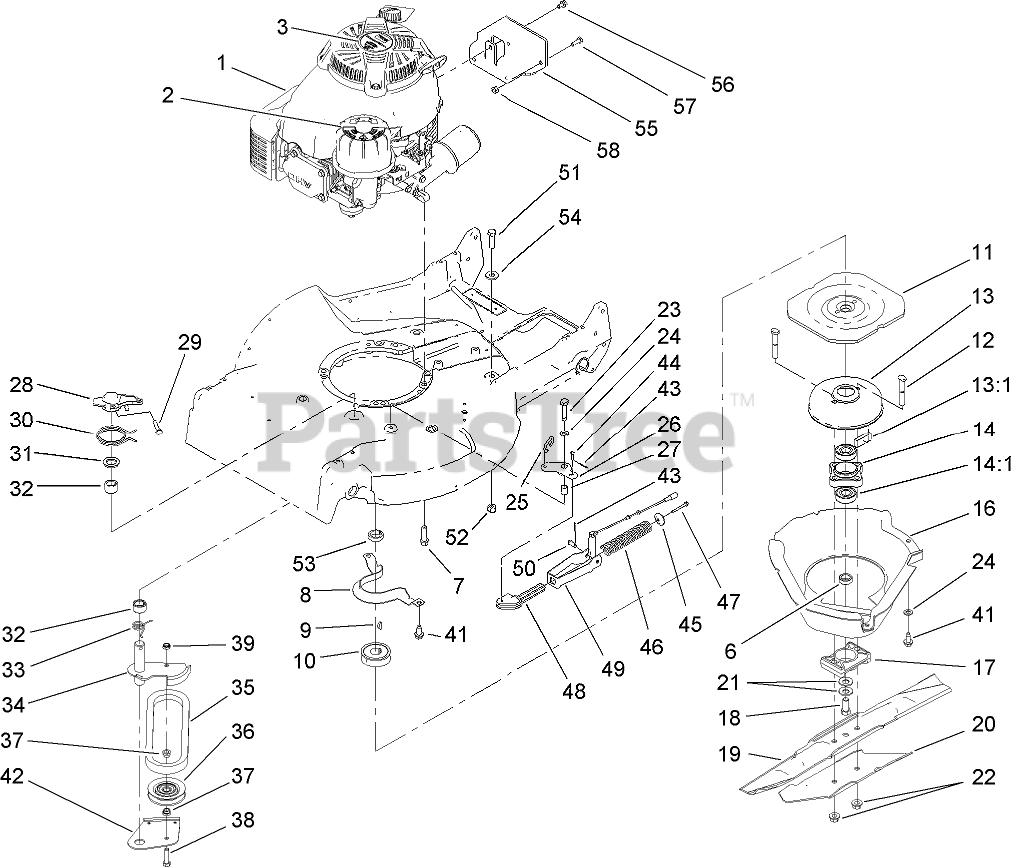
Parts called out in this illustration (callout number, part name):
1	ENGINE-KAWASAKI, FJ180V-AS36
3	DECAL
6	SPACER-SHAFT, OUTPUT
7	SCREW-TAPTITE
8	BRACKET-GUIDE, BELT
9	KEY-WOODRUFF
10	PULLEY-DRIVER
11	FLYWHEEL-BBC
12	BOLT-BLADE
13	BRAKE DRUM ASM
13:1	DAMPENER-VIBRATION
14	HUB ASM
14:1	BEARING-BALL
16	SHIELD
17	SPACER-BLADE
18	SCREW-HH
19	BLADE-21 INCH
20	STIFFENER-BLADE
21	WASHER-SPRING
22	NUT-LOCK
23	SCREW-HH
24	WASHER-PLAIN
25	LINK-CONTROL
26	BELLCRANK
27	SLEEVE-BELLCRANK
28	LEVER
29	SCREW-HH
30	SPRING-TORSION
31	WASHER
32	BEARING
33	SPRING-TORSION
34	ARM-IDLER
35	V-BELT
36	PULLEY-IDLER
37	SPACER-PULLEY, IDLER
38	SCREW-HH
39	NUT-LOCK, NI
41	SCREW-HWHTF
42	BRAKE PLATE ASM
43	PIN-COTTER
44	PIN-SPRING
45	RETAINER-SPRING
46	SPRING
47	SCREW-HWHTF
48	GUIDE-SPRING
49	BRACKET-SPRING
50	PIN-CABLE
51	SCREW-HH
52	NUT-LOCK, NI
53	SPACER-PULLEY
54	WASHER-HARDENED
55	BRACKET-ADAPTER, TANK
56	SCREW-HWH
57	SCREW-HH
58	NUT-LOCK, NI
